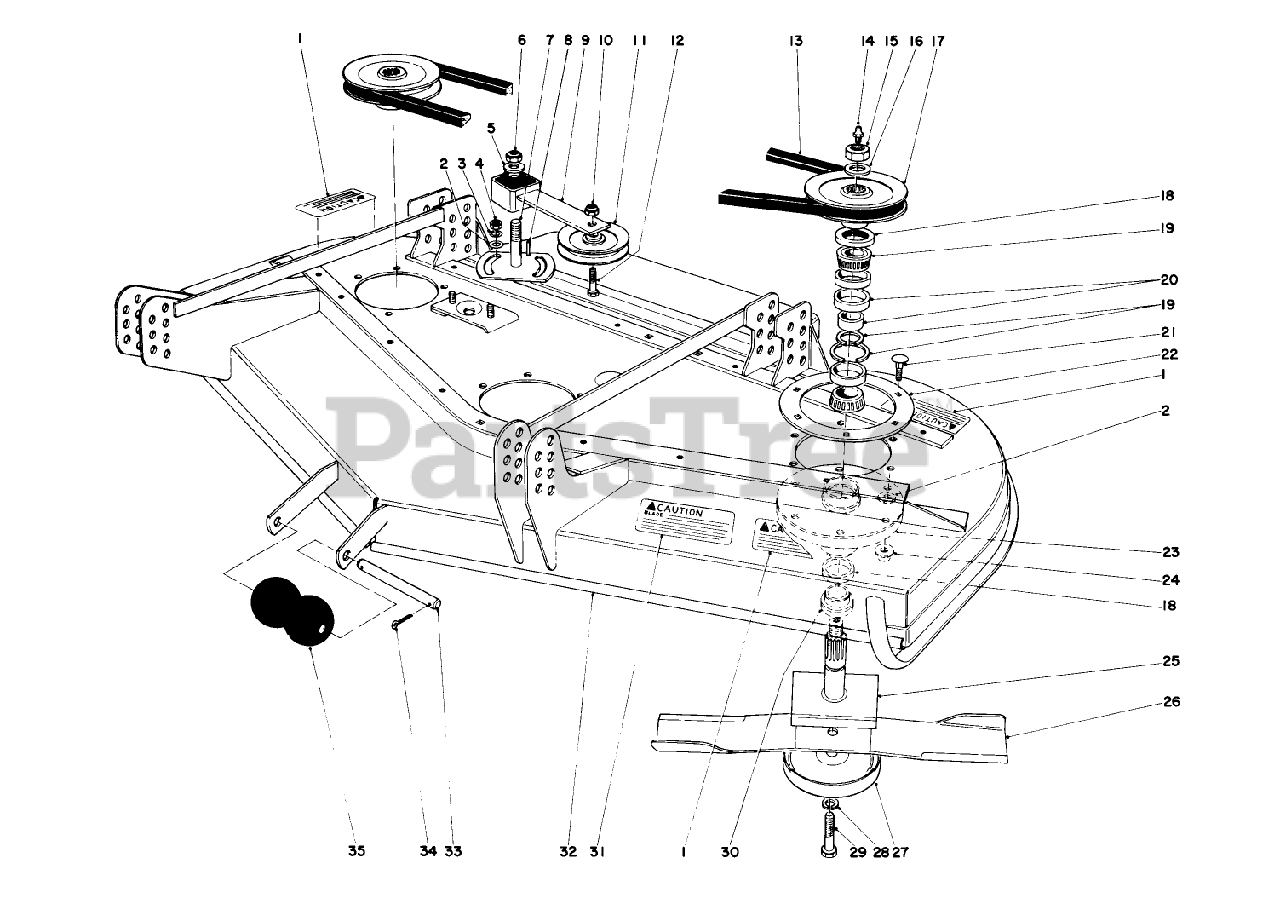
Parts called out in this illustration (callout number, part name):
1	DECAL-CAUTION, BLADE
2	WASHER-FLAT
3	WASHER-LOCK
4	NUT-JAM
5	WASHER-FLAT
6	NUT-LOCK, NI
7	PLATE-IDLER
8	KEY-SQUARE
9	IDLER ARM ASM
10	NUT-HEX
11	Idler Pulley
12	SCREW-HH
13	V-BELT
14	FITTING-GREASE
15	NUT-HEX
16	WASHER
17	PULLEY AND HUB ASM
18	SEAL-OIL
19	BEARING ASM
20	SPACER-SET, MATCHED
21	SCREW-CARR
22	SUPPORT-DECK, RING
23	Housing-Spindle
24	NUT-HF
25	SHAFT
26	Blade
27	Cup-Scalp
28	WASHER-LOCK
29	Capscrew
30	SPACER
31	Decal-Caution
32	CUTTER DECK WA RO
33	SHAFT-ROLLER
34	PIN-COTTER
35	ROLLER
